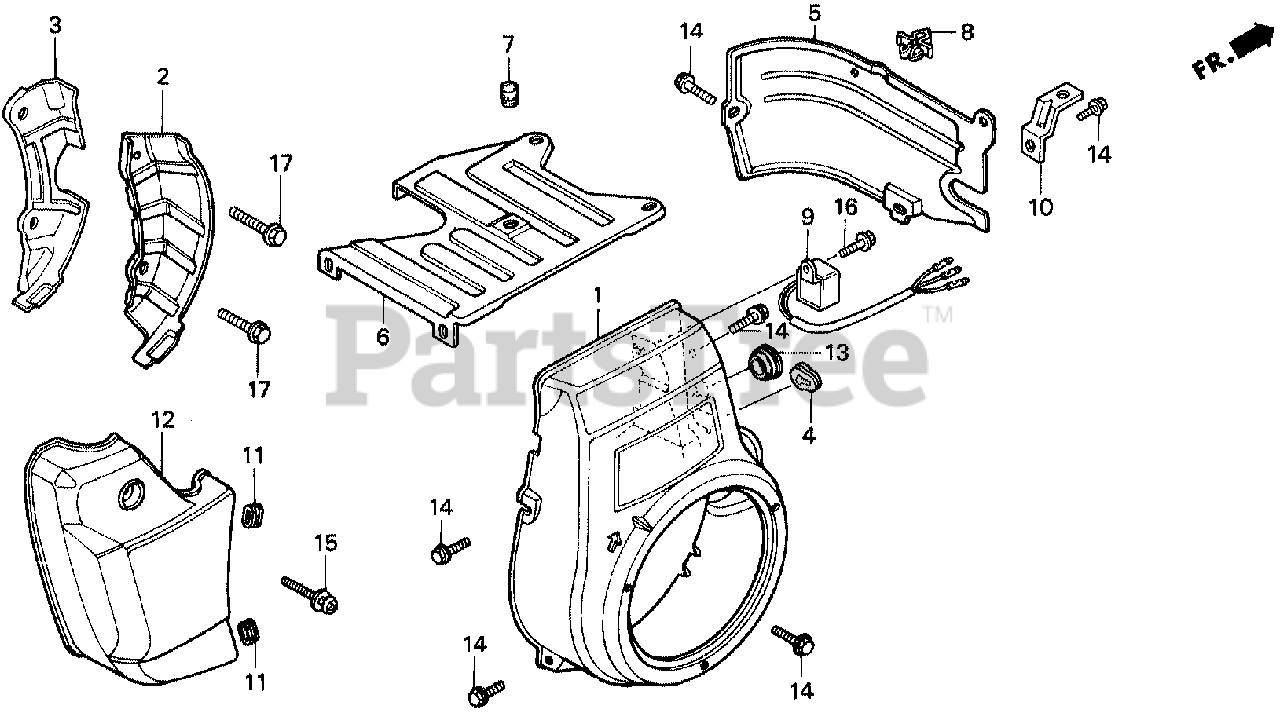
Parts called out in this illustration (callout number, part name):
1	COVER, FAN *R8* (BRIGHT RED)
2	PLATE, SIDE
6	COVER, TOP
7	GROMMET, COVER
8	CLIP, IGNITION WIRE (8MM)
11	RUBBER, CHAIN CASE SETTING
12	COVER, ENGINE SIDE *R8* (BRIGHT RED)
13	GROMMET, DRAIN HOLE
14	BOLT, FLANGE (6X12) (CT200)
15	SCREW-WASHER (6X28)
17	BOLT, FLANGE (8X20)
